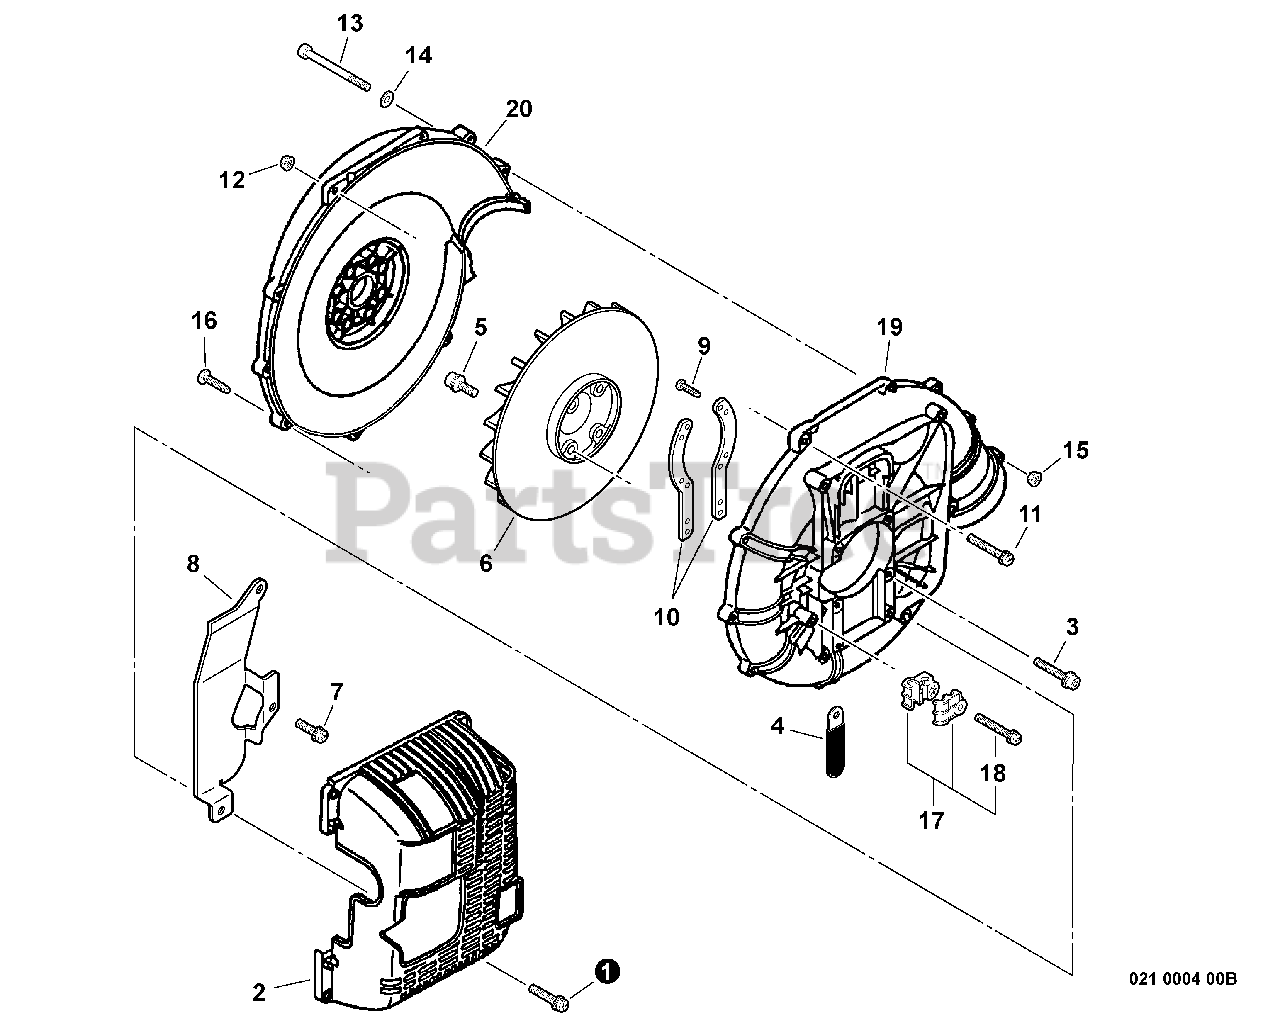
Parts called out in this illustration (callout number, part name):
1	SCREW - 5X18
2	COVER, ENGINE
3	SCREW - 5X32
5	SCREW - 5X20
7	SCREW - 5X10
8	INSULATOR
9	SCREW - 3X12 -- TAPPING
10	BRACKET, ENGINE
11	SCREW - 5X40
12	NUT - 5 -- FLANGE
13	SCREW - 5X60
14	WASHER - 5
15	NUT - 5 -- FLANGE
16	SCREW - 5X30
17	CABLE HOLDER KIT
18	SCREW - 5X25
19	COVER, FAN - OUTER
20	COVER, FAN - INNER -- GRAY
